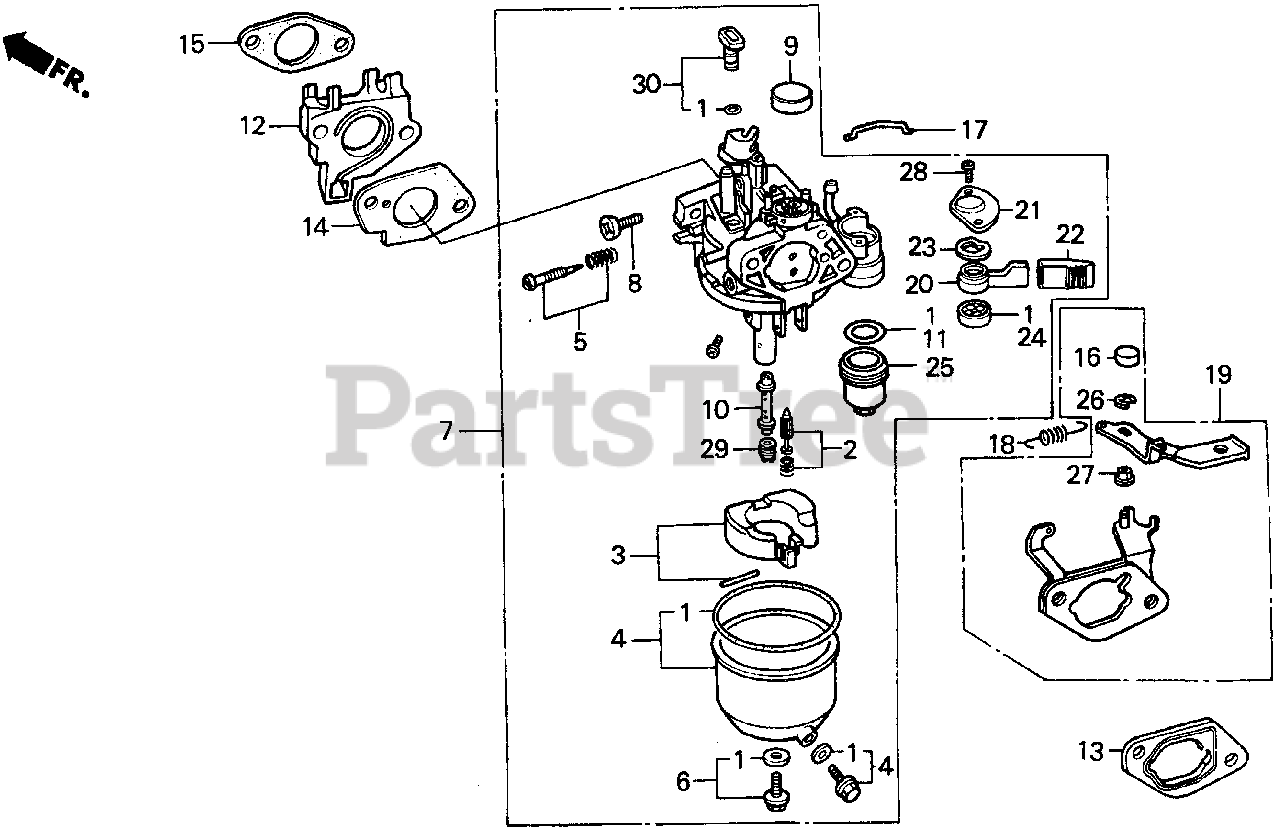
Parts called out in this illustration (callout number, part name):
1	GASKET SET
2	VALVE SET, FLOAT
4	CHAMBER SET, FLOAT
5	SCREW SET, PILOT
6	SCREW SET B
7	CARBURETOR ASSY. (BE17A C)
7	CARBURETOR ASSY. (BE17A D)
7	CARBURETOR ASSY. (BE17A E)
8	SCREW, THROTTLE STOP
9	CAP, CHOKE LEVER DUST
10	NOZZLE, MAIN
11	GASKET, FUEL STRAINER CUP
12	INSULATOR, CARBURETOR
13	SPACER, CARBURETOR
14	GASKET, CARBURETOR
15	GASKET, INSULATOR
16	CAP, CHOKE LEVER
17	ROD, CHOKE
18	SPRING, CHOKE RETURN
18	SPRING, THROTTLE RETURN
19	STAY ASSY., CHOKE CONTROL
20	LEVER, VALVE
21	PLATE, LEVER SETTING
22	CAP, LEVER
23	SPRING, VALVE LEVER
24	GASKET, VALVE
25	CUP, FUEL STRAINER
26	E-RING (4MM)
27	BUSH, CHOKE LEVER
28	SCREW, PAN (3X8)
29	JET, MAIN (#88)
29	JET, MAIN (#90)
29	JET, MAIN (#92)
30	JET SET, PILOT (#38)
